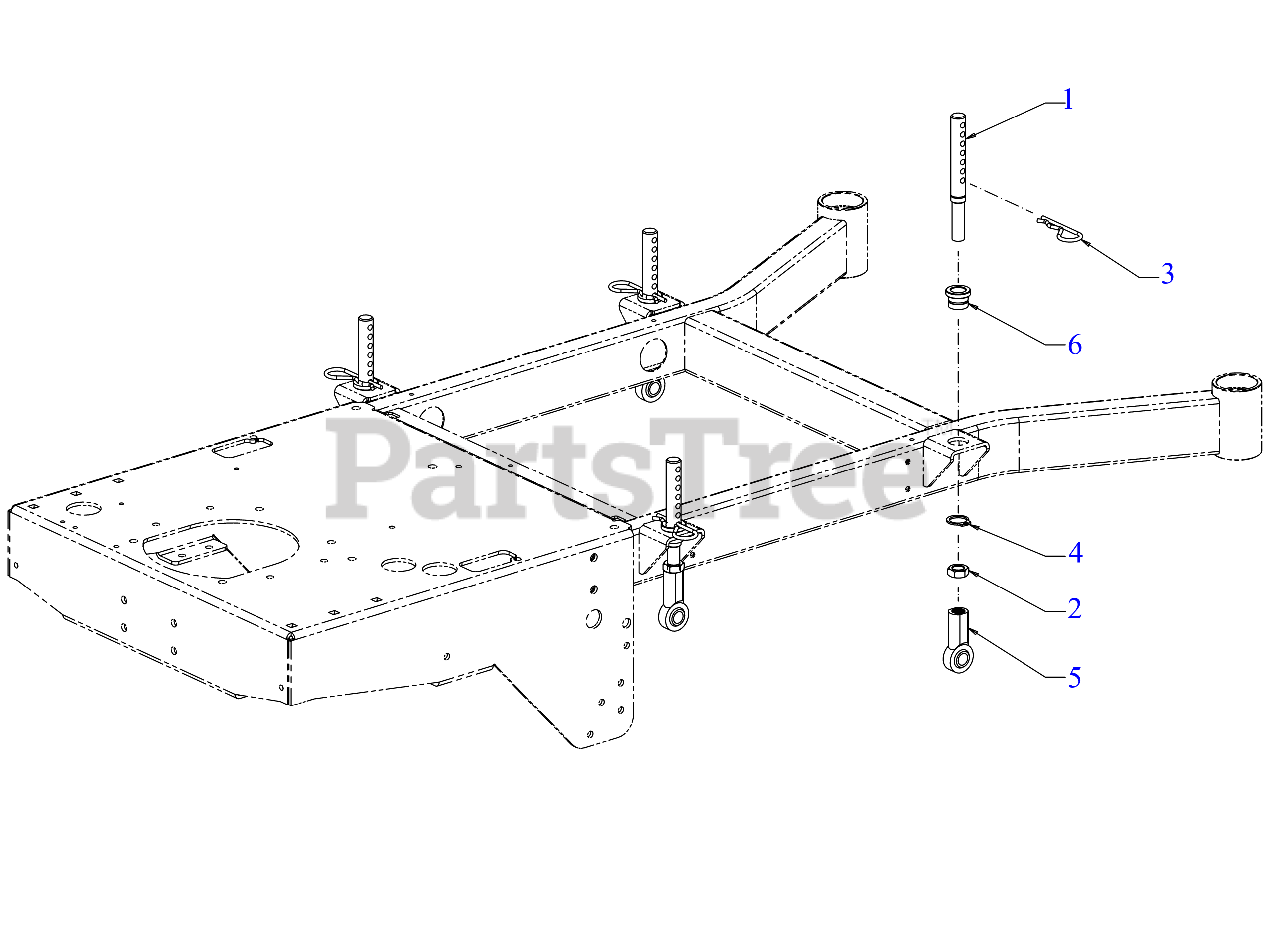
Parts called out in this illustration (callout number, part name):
1	DECK LIFT ADJUSTMENT PIN
2	HEX JAM NUT 5/8-18
3	COTTER PIN (.177 x 3.5)
4	RETAINING RING
5	BALL JOINT ROD END
6	FLANGE BUSHING (.75 ID x .875 LG)
